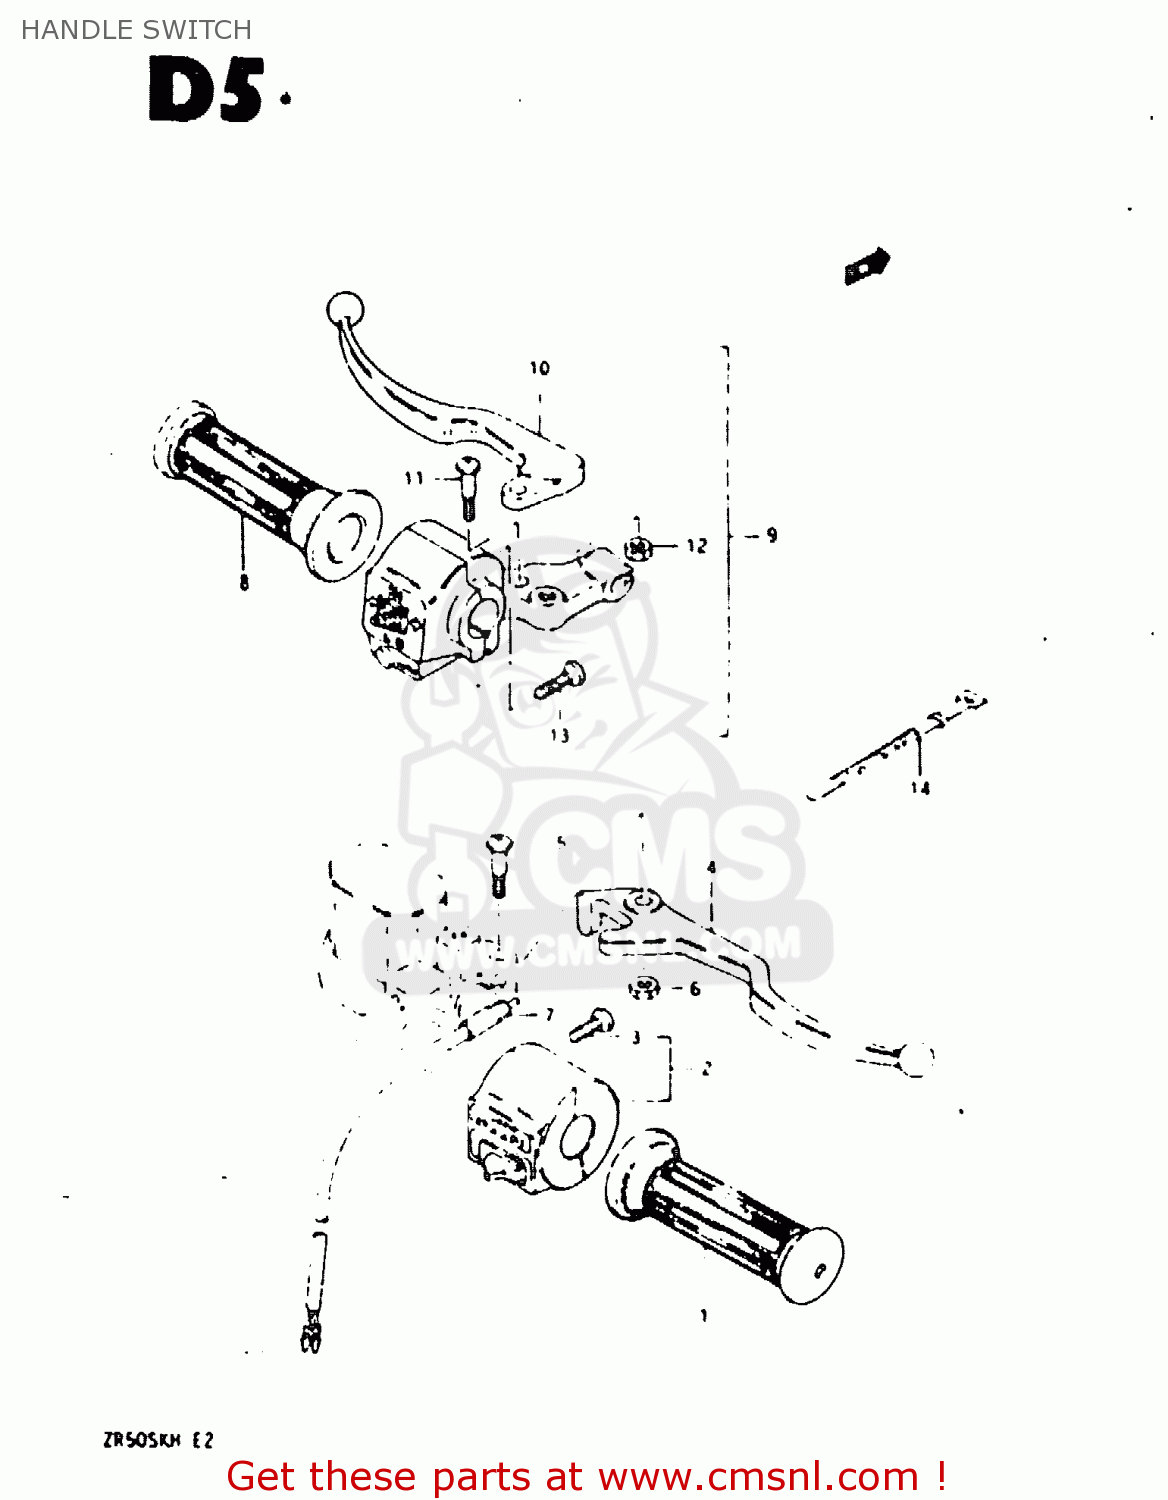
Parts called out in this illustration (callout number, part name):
1	GRIP, THROTTLE
2	SWITCH ASSY, HANDLE RH
3	SCREW 5X20
4	LEVER,BRAKE
5	SCREW
6	NUT
7	SWITCH ASSEMBLY
8	GRIP, LH
9	LEVER ASSY, CLUTCH
10	LEVER,CLUTCH
11	SCREW
12	NUT 8MM
13	SCREW 5X20
14	CLAMP(L:120)
